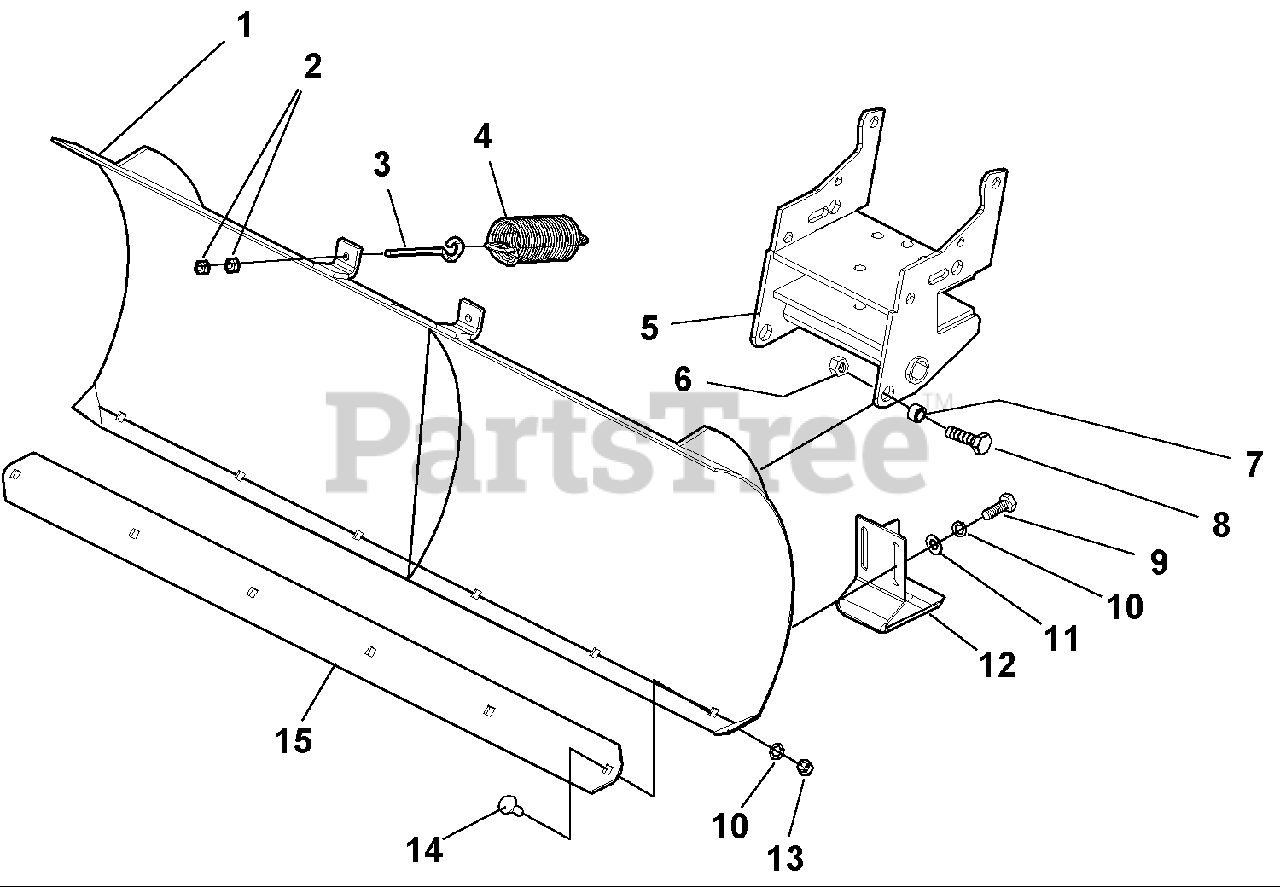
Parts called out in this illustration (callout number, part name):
1	BLADE ASSEMBLY
2	NUT, Hex, 5/16-18
5	FRAME ASSEMBLY
6	NUT, Centerlock, 1/2-13
8	CAPSCREW, Hex Head, 1/2-13 x 1-1/2
9	CAPSCREW, Hex Head, 3/8-16 x 3/4
10	LOCKWASHER, 3/8
11	WASHER, 3/8
12	SHOE ASSEMBLY
13	NUT, Hex, 3/8-16
14	CARRIAGE BOLT, 3/8-16 x 1
15	WEAR PLATE
